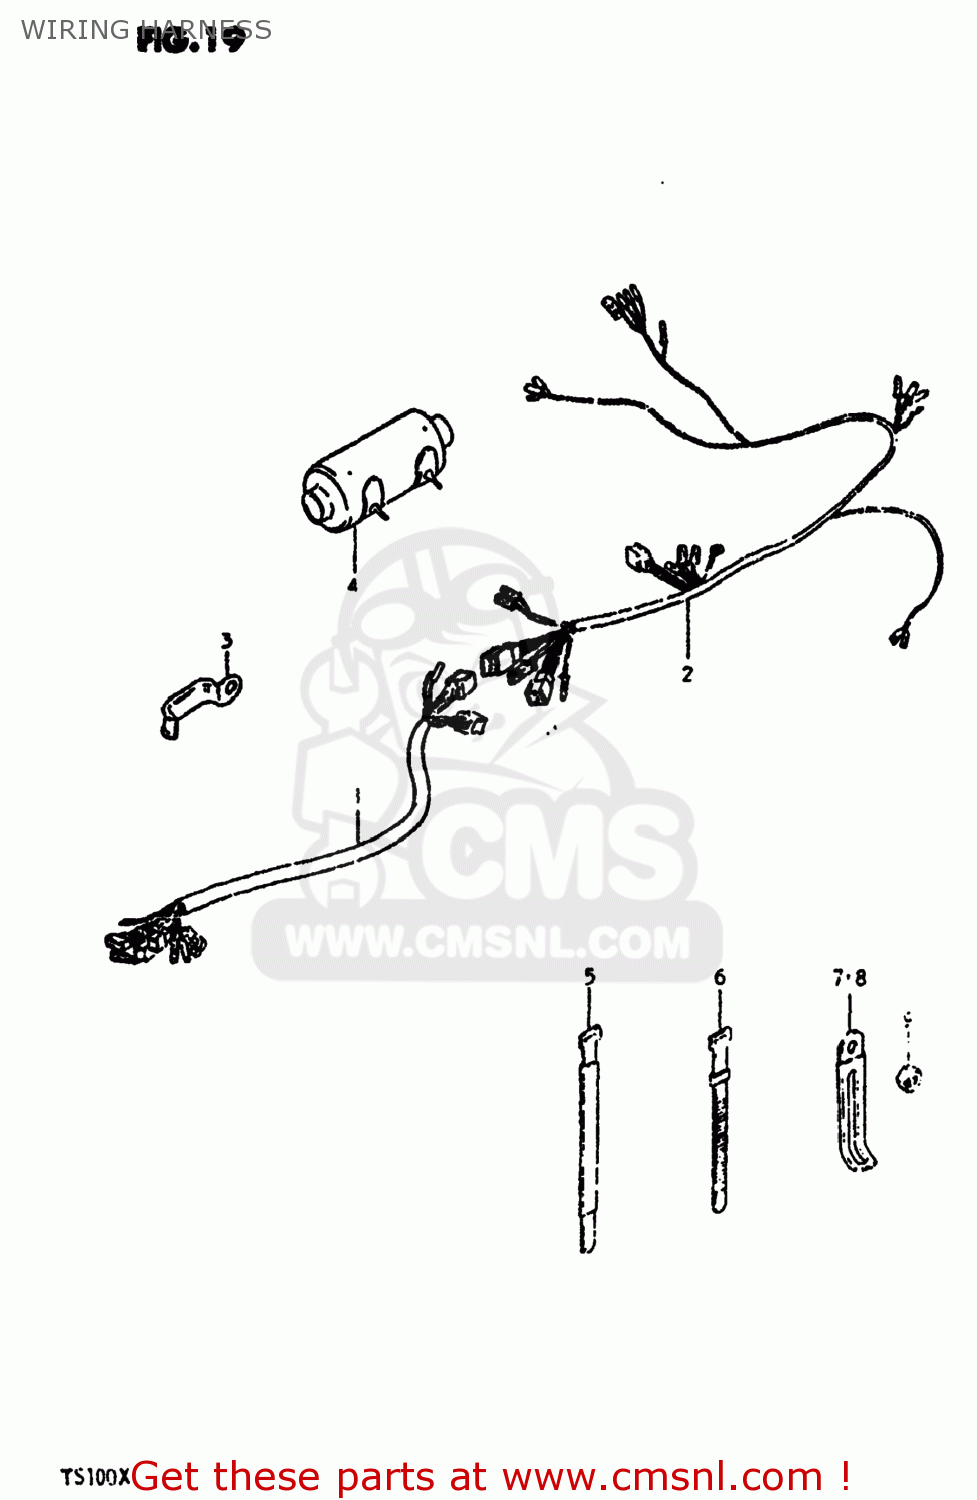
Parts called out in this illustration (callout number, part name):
1	HARNESS,WIRING
2	HARNESS,WIRING NO.2
3	CLAMP
4	BOOT,WIRING HARNESS
5	CLAMP
6	CLAMP(L:120)
7	CLAMP
8	CLAMP
9	NUT
